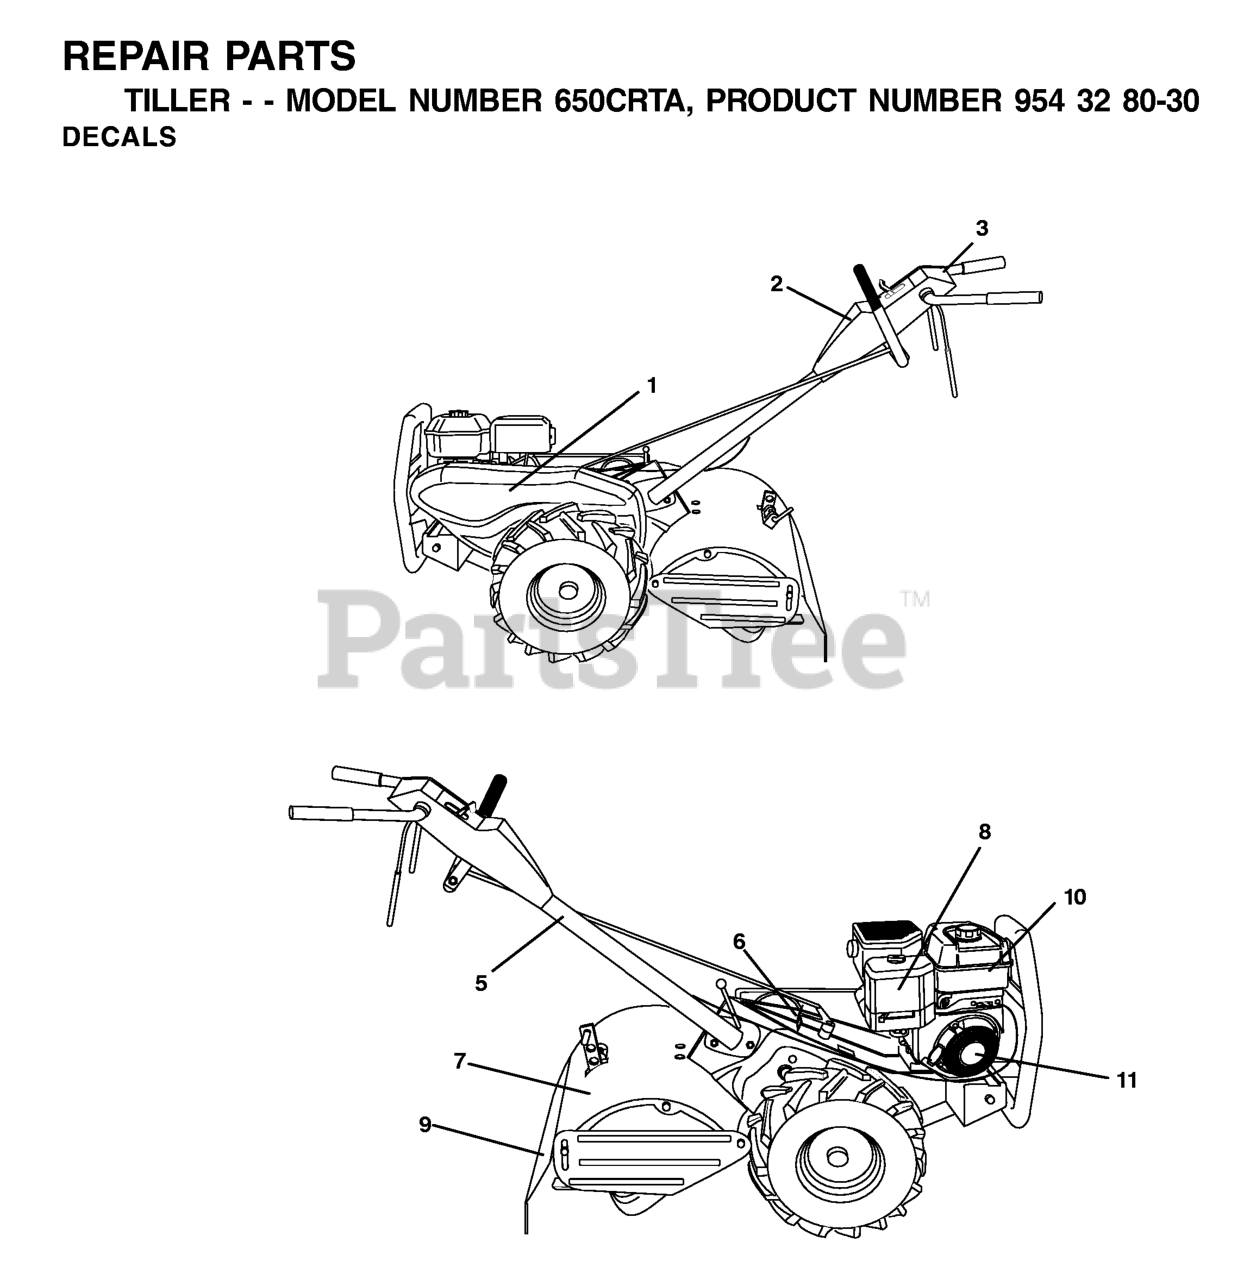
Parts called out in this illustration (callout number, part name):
1	DECAL, BOLT GUARD
2	DECAL, CTRL PANEL
3	DECAL, LOGO
5	DECAL TI (2 2)
6	DECAL.SHIFT.INDICATOR.TILLER
7	DECAL -CAUTION
8	DECAL, ENG. B&S 6.5HP
9	DECAL TI
10	DECAL, ENG. INTEK
11	DECAL.REWIND
